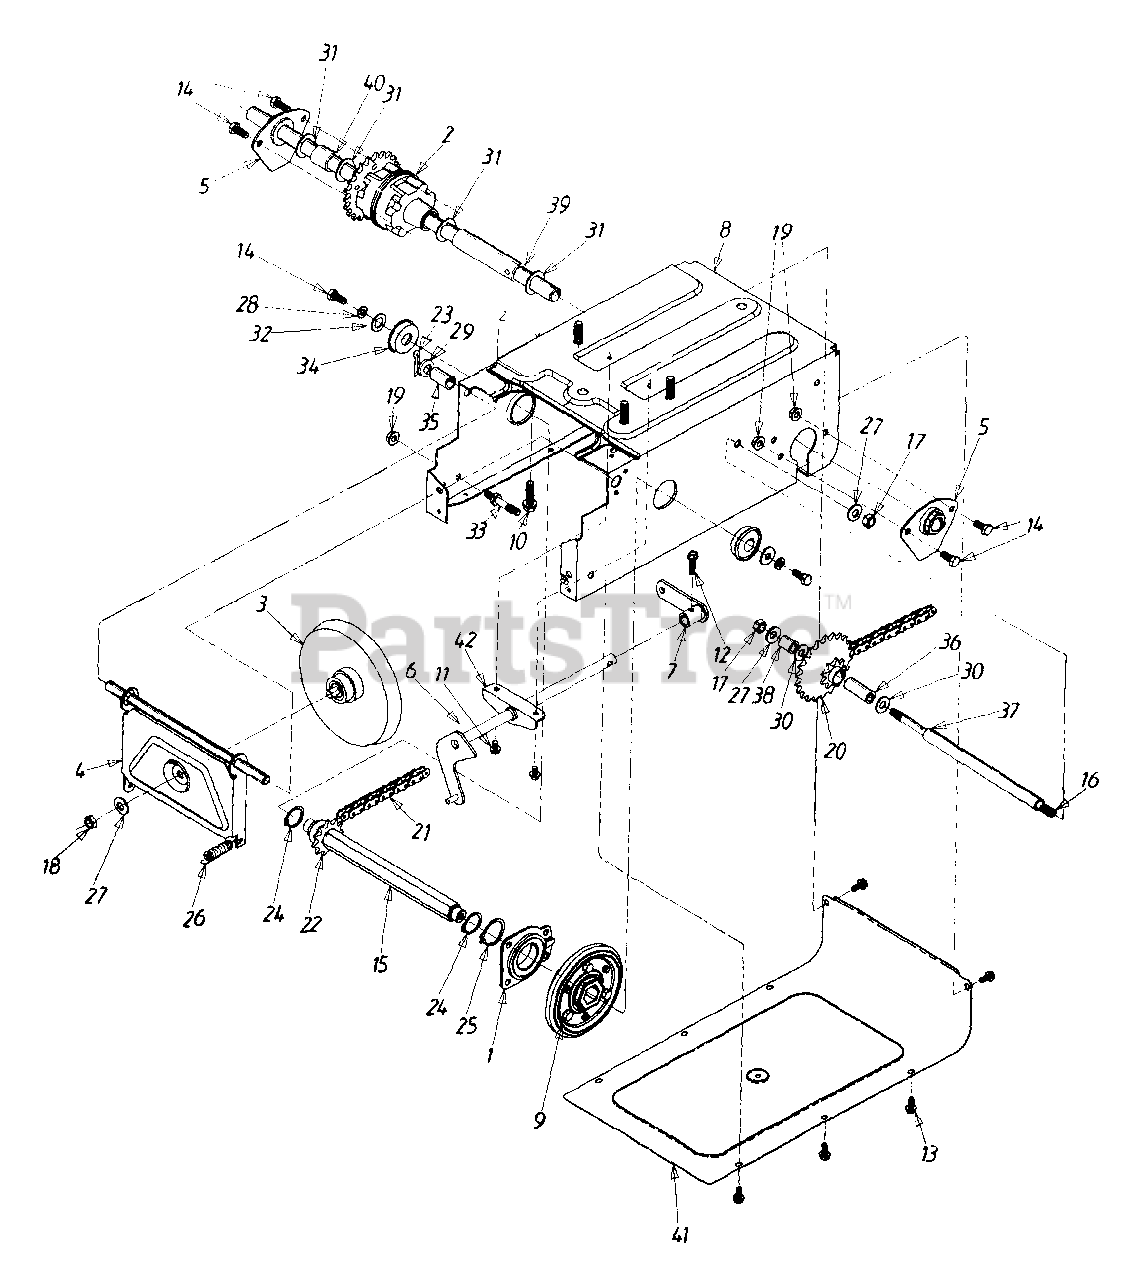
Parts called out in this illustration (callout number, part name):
1	BEARING ASSY - FRICTION WHEEL
2	DIFFERENTIAL ASSY COMP.
3	DISC - FRICTION WHEEL ASSY COMP.
6	SHAFT ASSY - SHIFT
9	WHEEL ASSY - FRICTION
10	SCREW - HEX SELF - TAP
11	SCREW - HEX WASHER
12	SCREW - HEX WASHER
16	SHAFT - JACK
18	NUT - HEX JAM
19	NUT - HEX FLANGE LOCK
20	SPROCKET & HUB
22	SPROCKET 11T
23	PIN - COTTER
26	SPRING - EXTENSION 1
27	WASHER - BELL
28	WASHER - LOCK
29	WASHER - FLAT
30	WASHER - FLAT
31	WASHER - FLAT
32	WASHER - FLAT
33	BOLT - IDLER
34	BEARING - BALL
